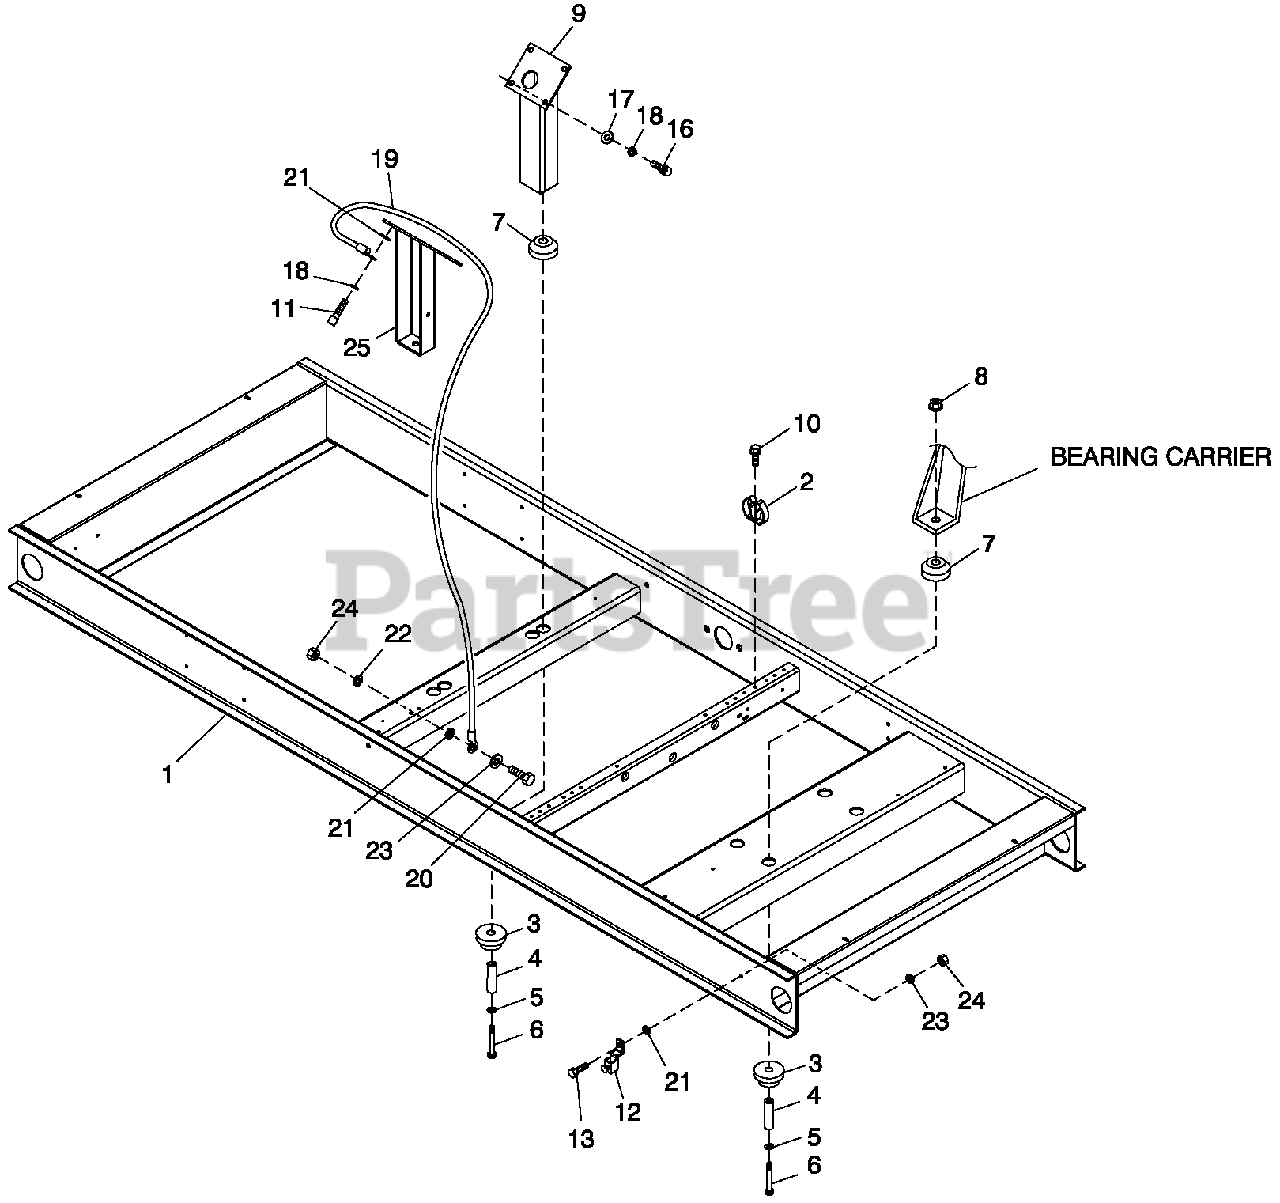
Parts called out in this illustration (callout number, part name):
1	BASE CP 6.8L70KW/5.4L 55KW DD
2	SPRING CLIP HOLDER .37-.62
3	DAMPENER VIBRATION
4	SPACER .49 X .62 X 1.87 PWDR/ZINC
5	WASHER FLAT M12
6	SCREW HHC M12-1.75 X 85 G8.8
7	DAMPENER VIBRATION 50 WHITE
8	NUT LOCKING M12-1.75
9	SUPPORT ENG 5.4L LH/RH 6.8L RH
10	SCREW HHTT M4-0.7X8BP
11	SCREW SHC M10-1.5 X 60 G12.9 (6.8L)
12	LUG SOLDERLESS 3/0-#4X 13/32 CU
13	SCREW HHC M8-1.25 X 25 G8.8
16	SCREW SHC M10-1.5 X 30 G 12.9
17	WASHER FLAT 3/8-M10 ZINC
18	WASHER LOCK M10
19	ASSY WIRE 14.00"
20	SCREW HHC M8-1.25 X 30 G8.8
21	WASHER SHAKEPROOFINT 3/8
22	WASHER LOCK M8-5/16
23	WASHER FLAT 5/16-M8 ZINC
24	NUT HEX M8-1.25 G8 YEL CHR
25	SUPPORT ENGINE LH (5.4L ONLY)
